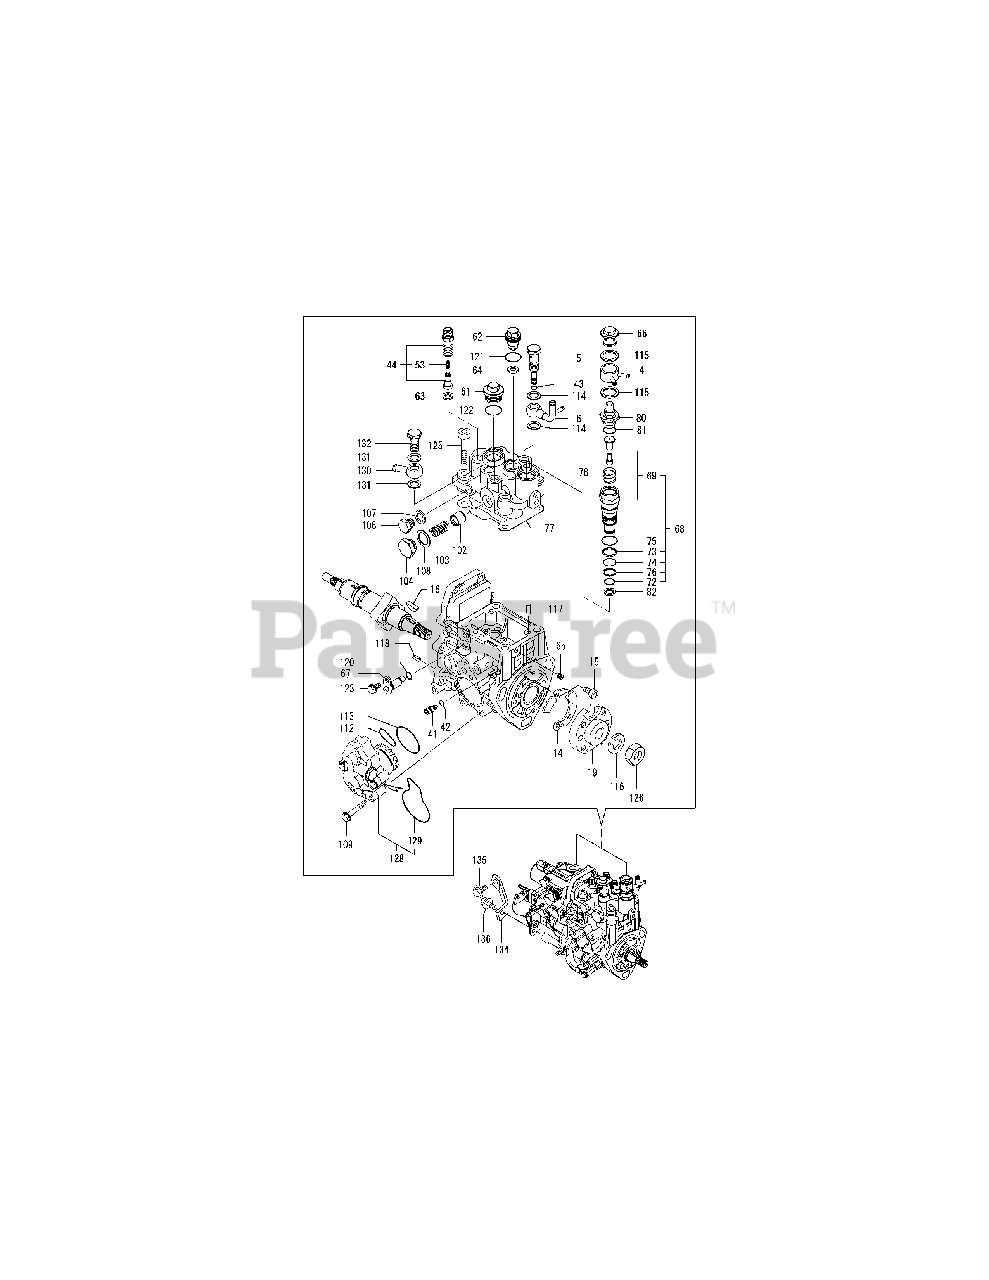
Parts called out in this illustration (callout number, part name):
1	INJECTION PUMP ASSY
4	JOINT, COOLING WATER
5	JOINT, OVER FLOW
6	JOINT, OVER FLOW
16	KEY, WOODRUFF 4X16
41	STOPPER, TAPPET
44	SETTING, DELIVERY
53	SPRING, DELIVERY
63	PK(BARREL PLUG
64	PK(BARREL PLUG
66	PLUG, WATER PUMP
75	PACKING, 19020
76	RING, BACKUP T2 P 15
80	ELEMENT, THERMO
103	SPRING, ACTUATOR
107	SEAL WASHER 12
114	SEAL WASHER 12
116	SPRING WASHER 14
117	PARALLEL PIN 5X14
118	SPRING PIN 5X10
120	O-RING 1A P-7.0
121	O-RING 4D 19018
122	PACKING, 19020
123	BOLT 6X 10 PLATED
126	LOCK NUT M14 PLATED
128	PUMP ASSY, FUEL FEED
130	JOINT, PIPE 12
131	SEAL WASHER 12
132	JOINT BOLT 6,PIPE
134	RETAINER, PUMP
135	BOLT M 8X 16 PLATED
136	BOLT M 8X 20 PLATED
